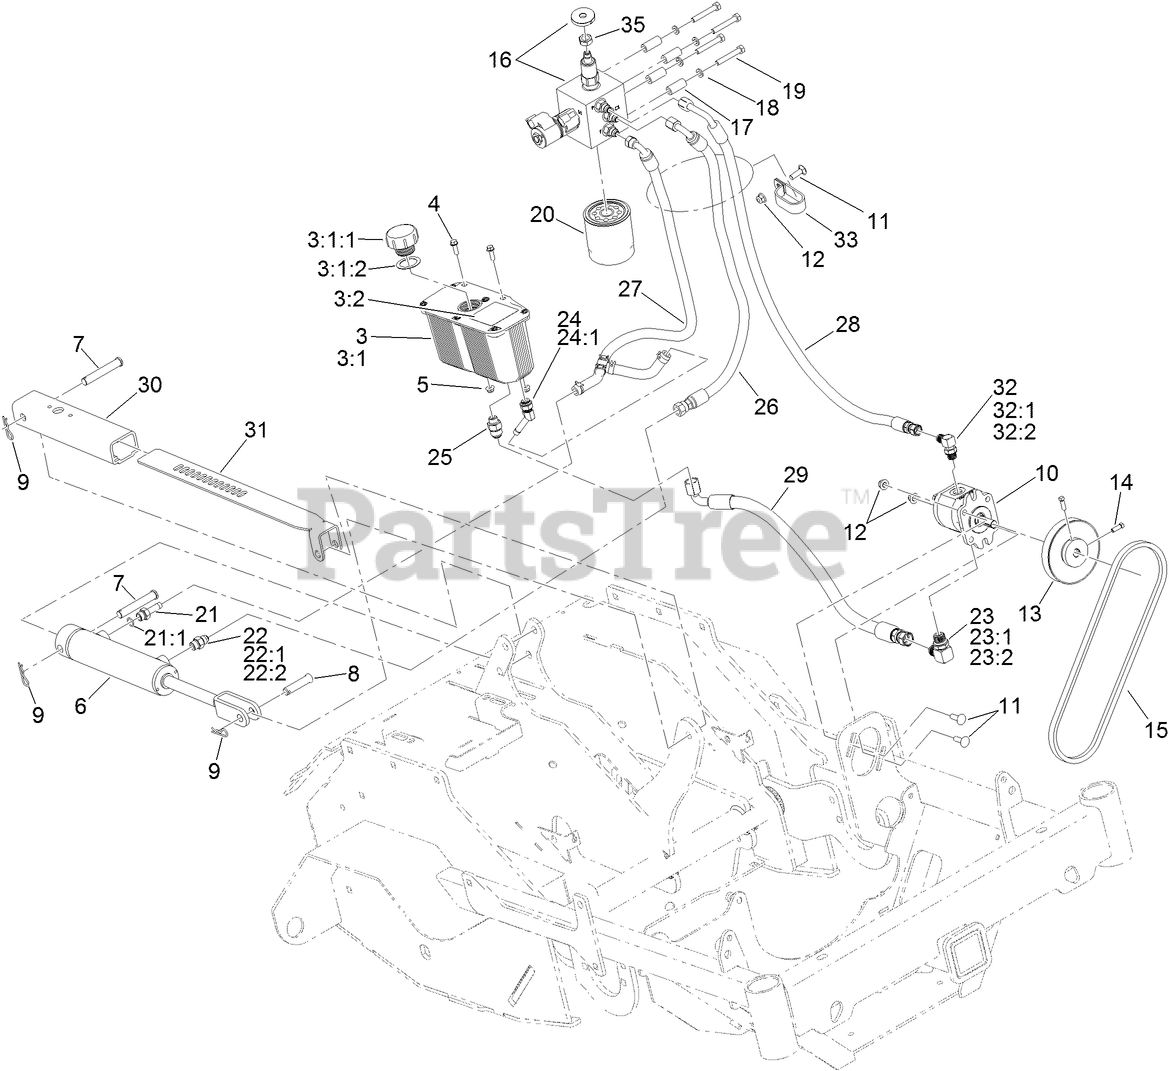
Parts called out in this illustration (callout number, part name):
3	RESERVOIR ASM
3:1	Reservoir-HYD
3:1:1	CAP-RESERVOIR, HYD
3:1:2	GASKET-CAP
3:2	DECAL-WARNING
4	SCREW-HWH
5	NUT-HF
6	CYLINDER-HYDRAULIC
7	PIN-CLEVIS
8	PIN-CLEVIS
9	PIN-HAIR
10	PUMP-HYDRAULIC
11	SCREW-CARR
12	NUT-HF, NI
13	PULLEY
14	SCREW-SQH
15	BELT-V
16	MANIFOLD ASM
17	SPACER
18	WASHER-LOCK
19	SCREW-HH
20	FILTER-OIL, HYD
21	ADAPTER-STRAIGHT
21:1	O-RING
22	FITTING-STRAIGHT
22:2	O-RING
23	FITTING-90 DEG
23:1	O-RING
23:2	O-RING
24	FITTING-BARBED, 45 DEG
24:1	O-RING
25	FITTING-STR
26	HYDRAULIC HOSE ASM
27	HYDRAULIC HOSE ASM
28	HYDRAULIC HOSE ASM
29	HYDRAULIC HOSE ASM
30	HOUSING-DEPTH CONTROL
31	BRACKET-DEPTH CONTROL
32	FITTING-90 DEG
32:2	O-RING
33	CLAMP-R, DOUBLE
35	NUT-JAM
